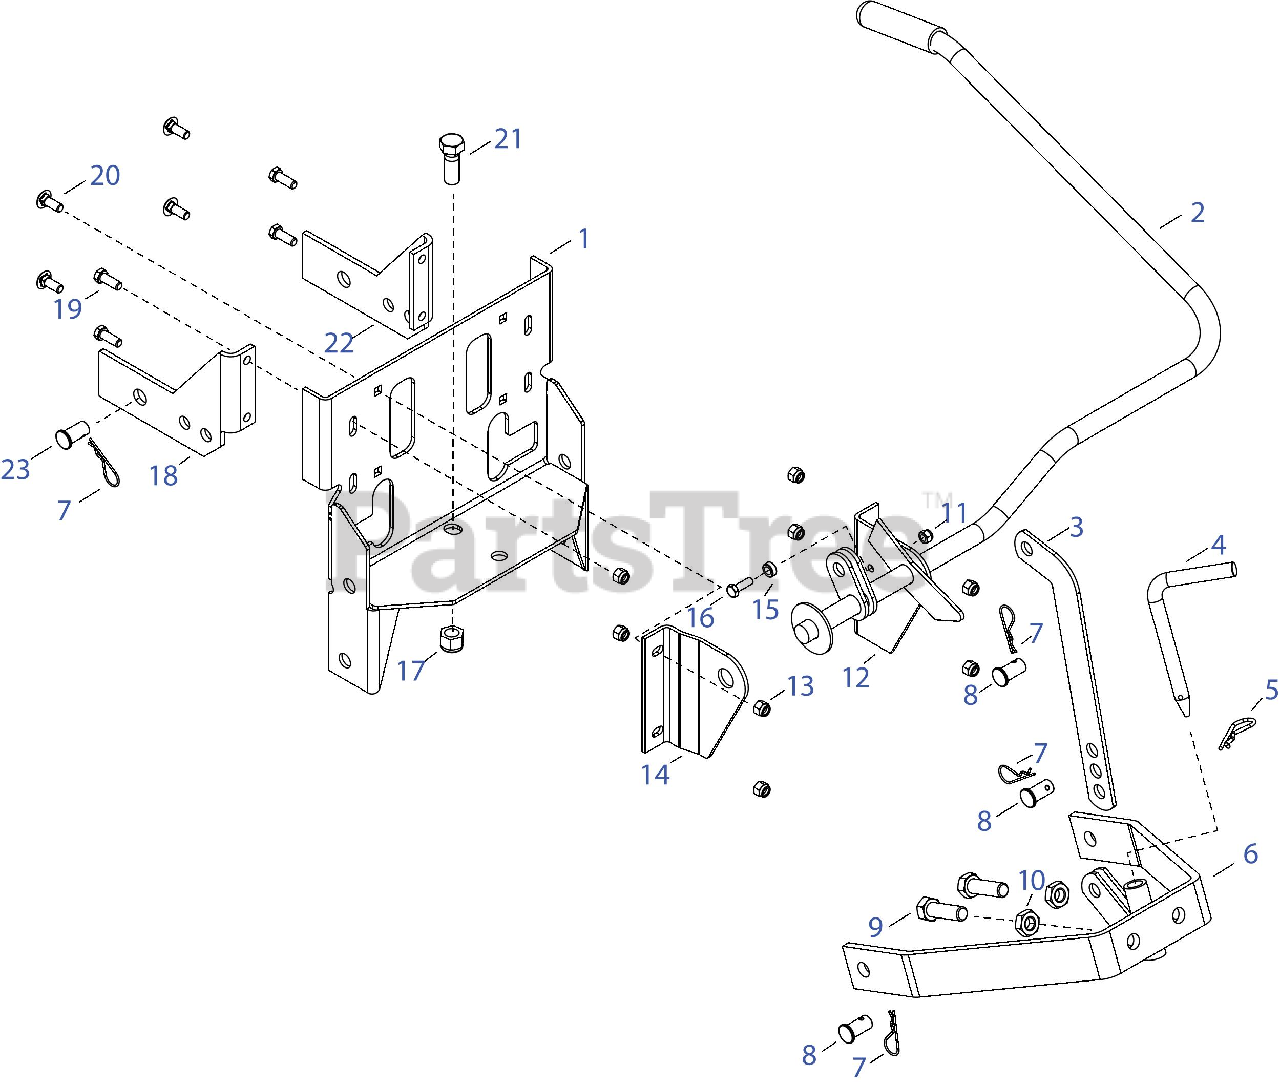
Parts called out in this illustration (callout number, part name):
1	Sleeve Hitch Frame
2	Lift Lever Assembly
3	Lifting Link Plate
4	Pin - Sleeve Hitch
5	Internal Cotter Pin
6	Sleeve Hitch Assembly
7	Hairpin Cotter 1/8
8	Clevis Pin .62
9	Bolt - Hex 5/8-11 X 2"
11	Hex Nut Ins
12	Pivot Bracket - R.H.
13	Hex Nut Ins L-3/
14	Pivot Bracket - L.H.
15	Bushing-Pivot
17	Nut - Hex 5/8-11 Nylock
18	Sleeve Hitch Bracket LH
19	Hex Screw 3/8-16
21	Bolt - Hex 5/8-11 X 1-3/4"
22	Sleeve Hitch Bracket RH
23	Clevis Pin 5/8 x 1 3/4
